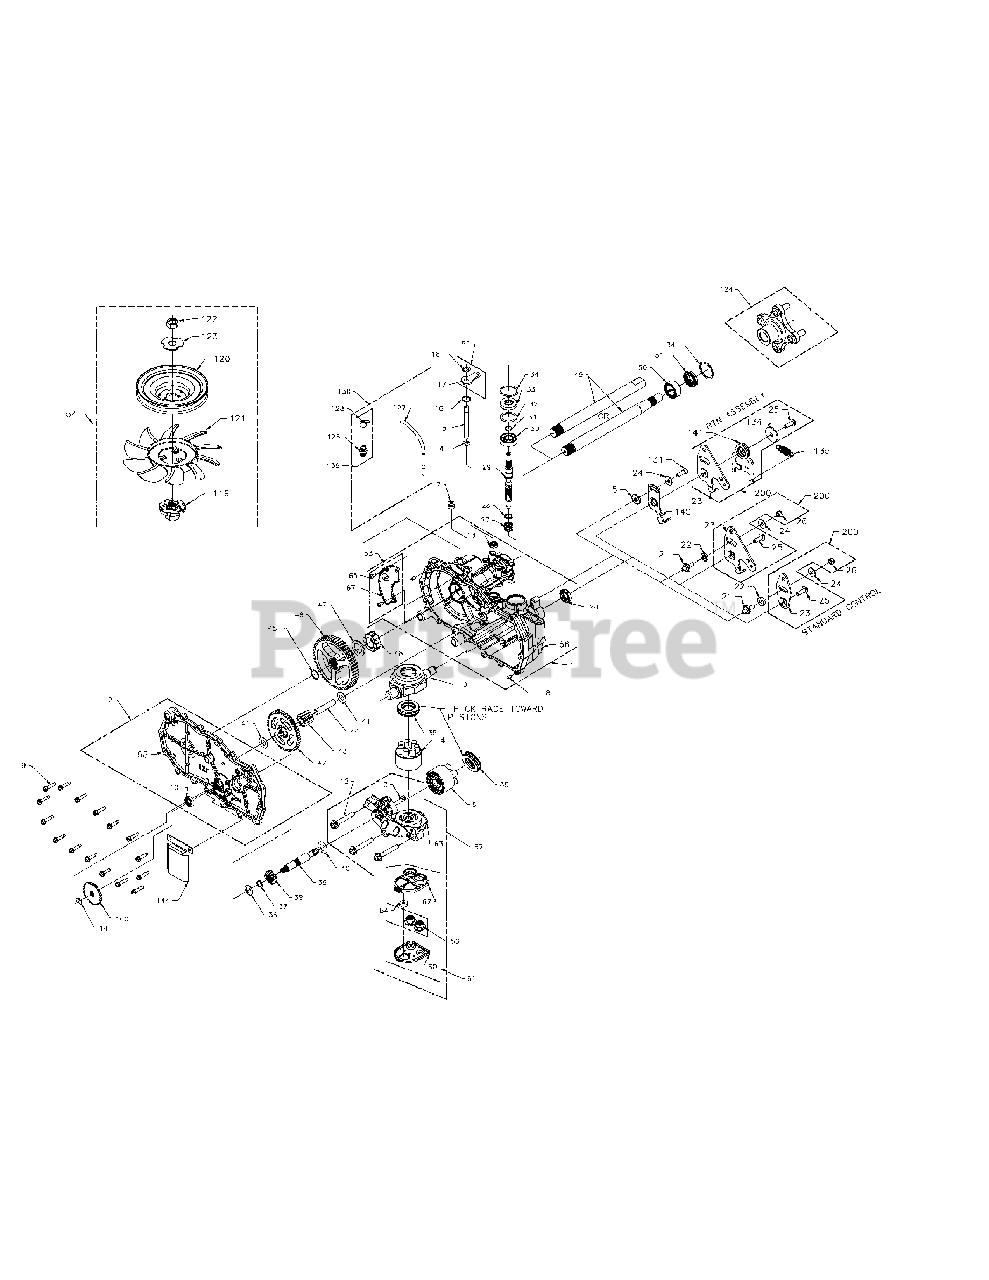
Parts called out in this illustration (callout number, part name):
1	RH W/CNTL AND BRAKE
2	COVER, SIDE, RH
3	PLATE, BYPASS
4	ASSEMBLY, PISTON BLOCK - 7P10CC
5	SPACER, .320 X 1.005
6	ASSEMBLY, PISTON BLOCK - 5P10CC
9	HFHCS 1/4-20 X 1.125 (SELF TAPPING)
12	BOLT, HEX FLANGE3/8-24 X 2.5
15	ROD, BYPASS
19	SWASHPLATE, TRUNNION, MACHINED
24	WASHER, .34 X .88
27	SPRING, HELICAL COMPRESSION
28	WASHER, .591 X .787 X .040
29	SHAFT, INPUT
30	BEARING, BALL 17MM ID X 40MM OD X 12MM
35	BEARING, THRUST 30 X 52 X 13
36	WASHER, 5/8 X 1.0 X .05
37	RING, RETAINING
38	GEAR, PINION 13T
39	SHAFT, MOTOR
40	WASHER, .71 X 1.16 X .04
41	WASHER, HT .5 ID X 1.0 OD X .032
42	GEAR. 10T/48T
43	GEAR, 1OT JACKSHAFT
44	PIN, JACKSHAFT
47	WASHER, 1.018 X 1.57 X .105
48	SLEEVE BEARING ( INBOARD)
49	SHAFT, AXLE, 1.0 x 11.7, DD
50	BEARING, SLEEVE, 1.00 X 1 .57 X .62
53	PLATE EXPANSION, RH
54	KIT-FAN & PULLEY
56	CHECK PLUG ASSEMBLY, .027, WASHER
57	KIT, CENTER SECTION, W/ FILTER-RH
59	KIT, BYPASS ARM W/ STUD
61	KIT, FILTER
63	CENTER SECTION, RH, 7P
127	HOSE, EXP TANK
131	KIT, RTN SCREWS
135	SPRING, EXTENSION
138	KIT, BREATHER ASSEMBLY
139	CAP KIT, BREATHER ASSEMBLY
140	NEUTRAL
200	KIT, RETURN, BIDIRECTIONAL
